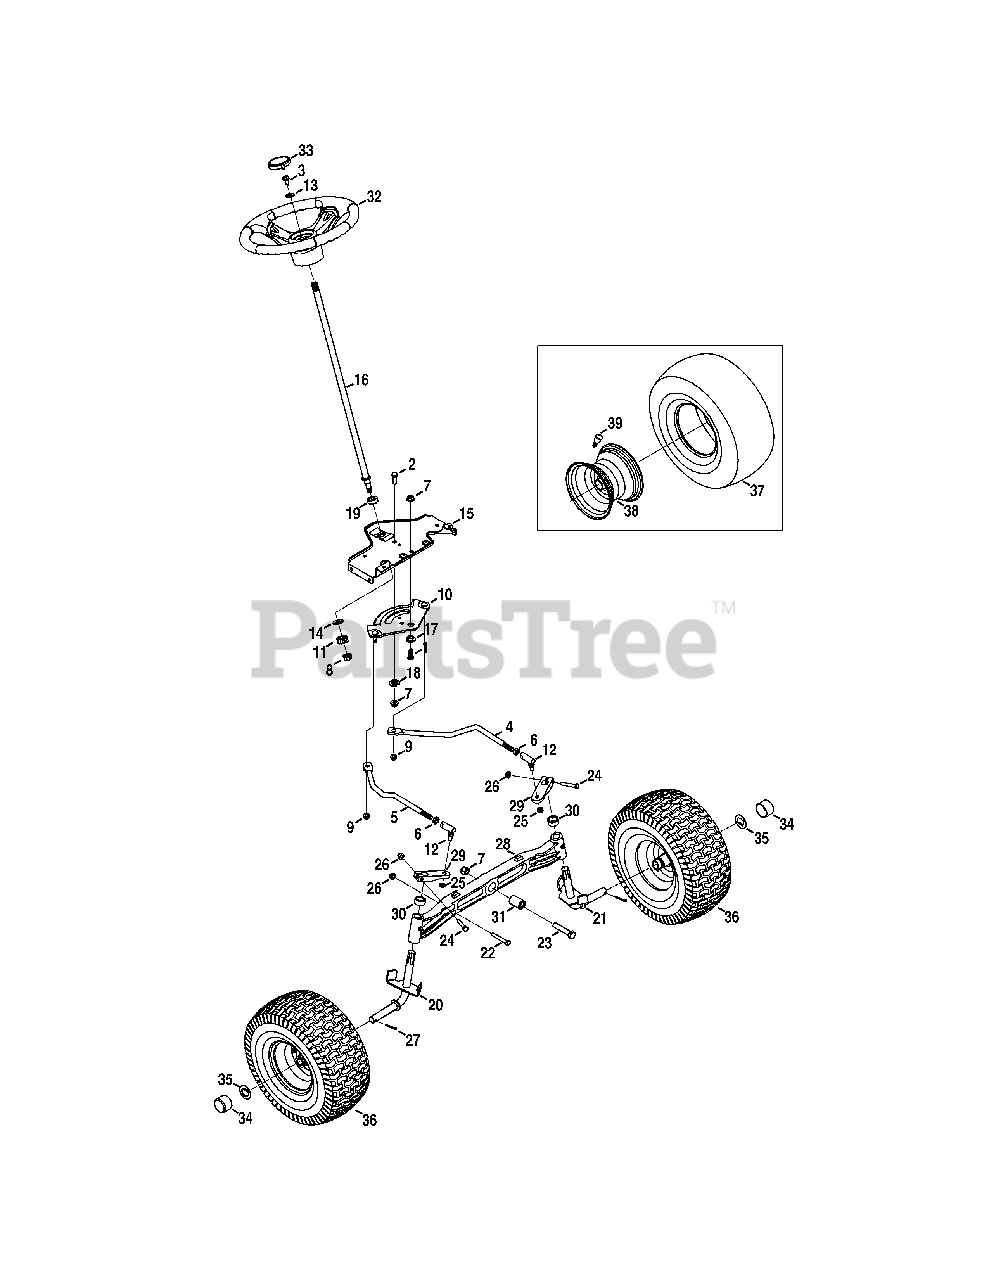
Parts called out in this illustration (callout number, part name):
1	Hex Head Screw, 3/8-16:1.00
2	Hex Head Screw, 3/8-16:1.00
3	Hex Head Screw, 5/16-18:1.00
4	LH Drag Link
5	RH Drag Link
6	Jam Nut, 7/16-20
7	Flangelock Nut, 3/8-16
8	Flangelock Nut, 7/16-20
9	Flangelock Nut, 5/16-18
10	Steering Gear
11	Steering Pinion Gear
12	Ball Joint, 7/16-20
13	Flat Washer, .406 x .875 x .105
14	Flat Washer, .51 x 1.12 x .06
15	Steering Support Bracket
15	Screw, .750 5/16-18
16	Steering Shaft, .625 OD x 24.25 LG
17	Shoulder Spacer, .385 x 1.25 x .3025
18	Spacer, .38 x 1.375
19	Hex Flange Bearing 5/8 PM
20	RH Axle Assembly
21	LH Axle Assembly
22	Hex Head Screw, 5/16-18:2.25
23	Hex Head Screw, 3/8-16:2.50
24	Hex Head Screw, 5/16-18:1.75
25	Hexlock Nut, 3/8-24
26	Flangelock Nut, 5/16-18
27	Cotter Pin, 5/32:1.25
28	Pivot Bar Axle
29	Steering Block
30	Spacer, .71 ID x .125 OD x .56LG
31	Spacer, .385 x 1.00 x 1.5075
32	Steering Wheel
33	Steering Wheel Cap
34	Bumper Cap
35	Flat Washer, .781ID x 1.590OD
36	Wheel Assembly
38	Rim Assembly
39	Tubeless Air Valve
